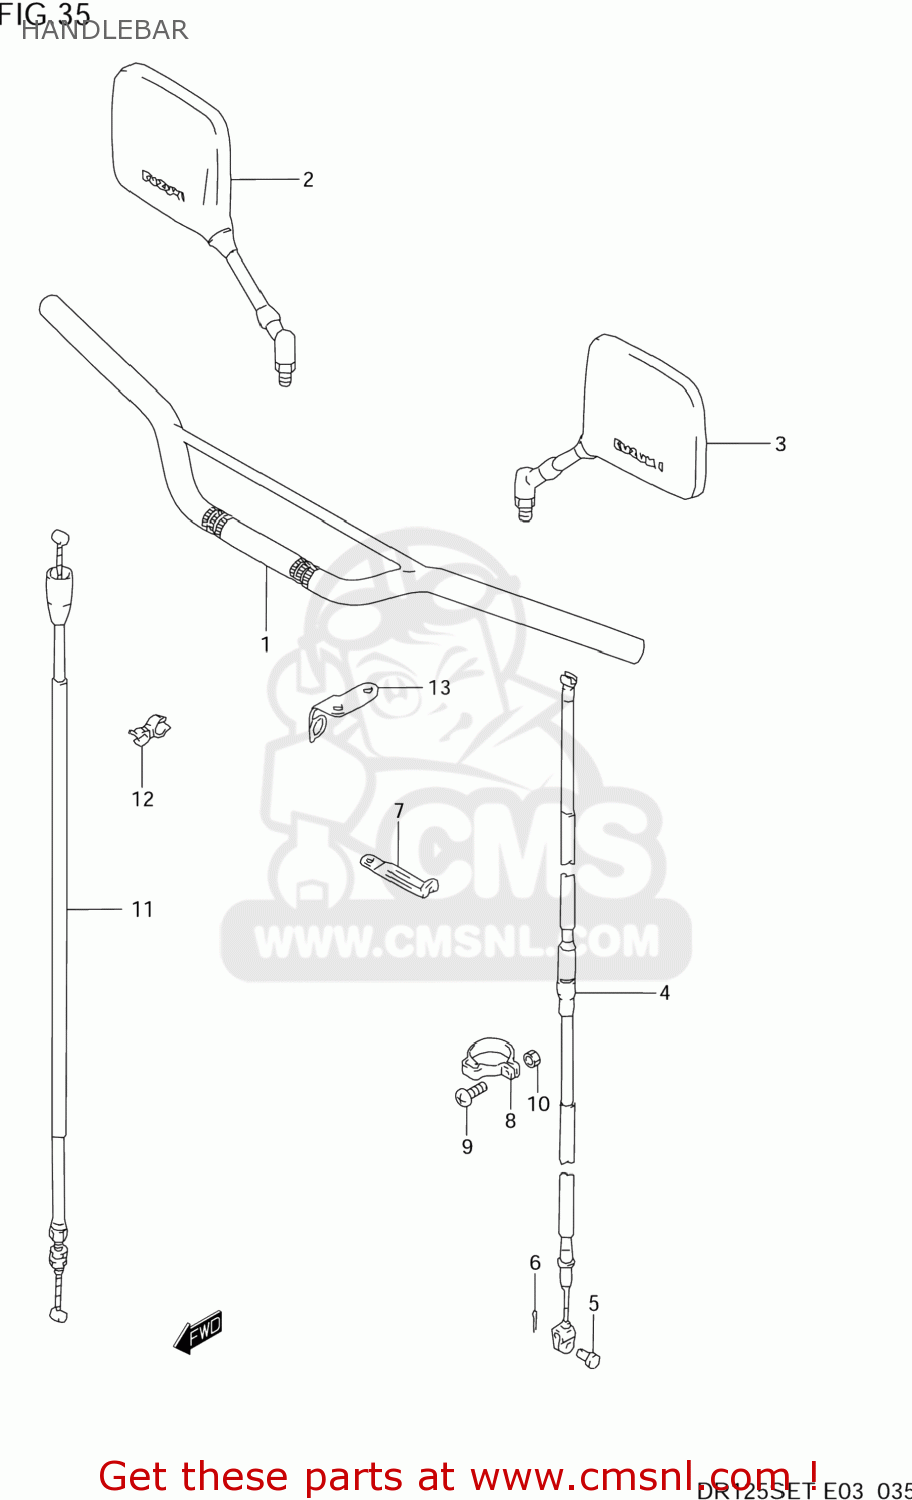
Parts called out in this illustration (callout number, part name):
1	HANDLEBAR(BLACK)
2	MIRROR ASSEMBLY,REAR VIEW
3	MIRROR ASSEMBLY,REAR VIEW
4	CABLE ASSEMBLY,CLUTCH
5	PIN(L:13)
6	PIN
7	CLAMP(L:235)
8	CLAMP,CABLE
9	SCREW
10	NUT
11	CABLE ASSY,THROTTLE
12	CLAMP
13	GUIDE,CABLE
